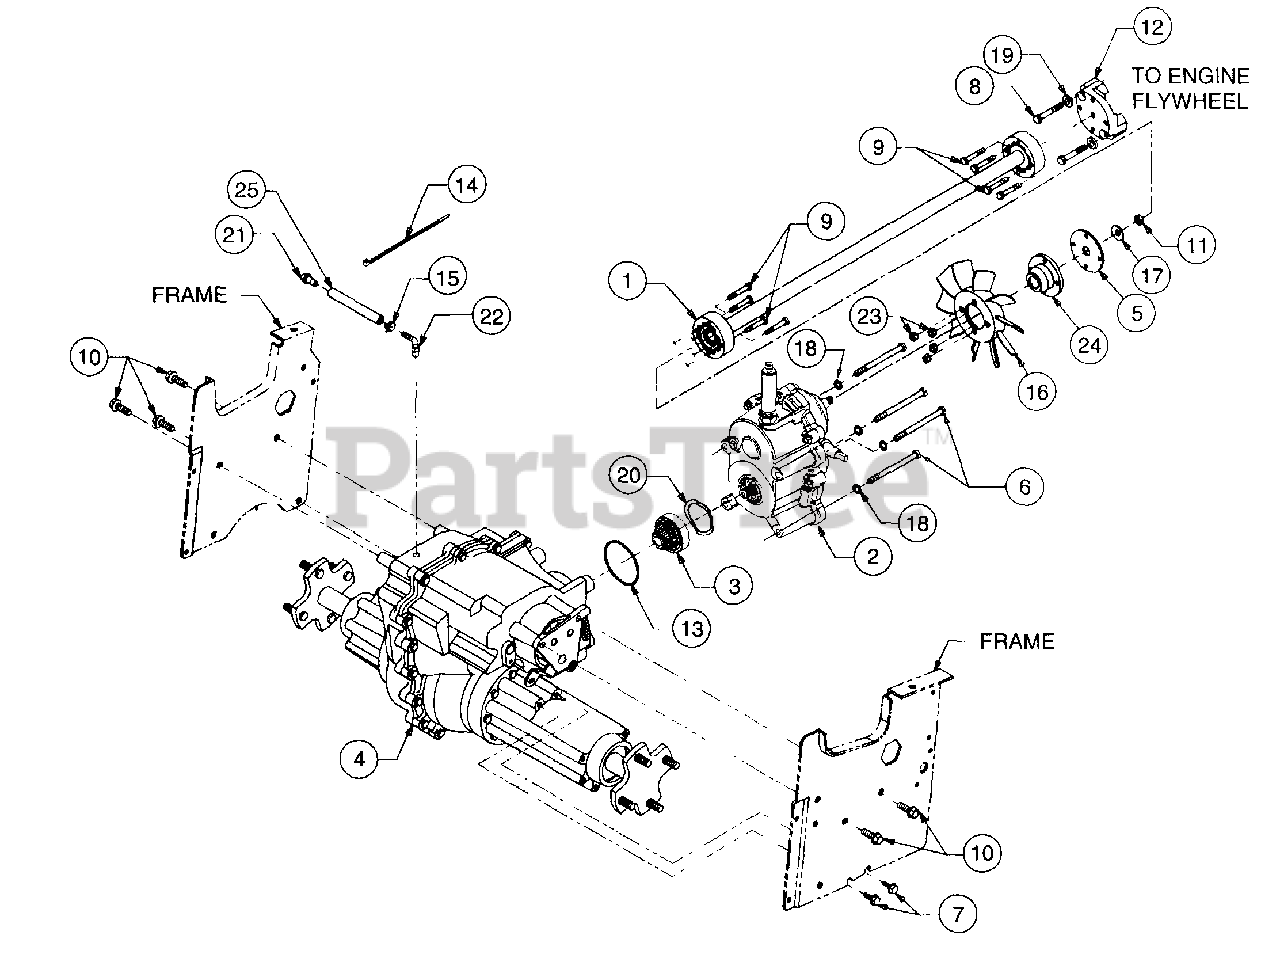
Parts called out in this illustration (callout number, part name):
1	Shaft Assy, Drive
2	Clutch Assembly
3	Pinion Assy, Input
4	Transmission Assy, 6-Speed
5	Plate, Drive Shaft Spacer
6	Screw, Hex Cap, 5/16-18 x 4.0 GR5
7	Screw, Hex Wash Hd Tapp 5/16-18 x .75
8	Screw, Hex Patch, M8-1.25 x 50mm
9	Screw, Hex Patch, 1/4-20 x 1.62 GR5
10	Screw, Hex Wash Hd Tp 3/8-16 x 1.25
11	Nut, Hex Center Lock Jam, 3/8-24
12	Adapter, Drive Shaft
13	O-Ring, 2.75 x .103
14	Tie, Self-Clinch Cable
15	Clamp, Hose
16	Fan, 10 Blade Cooling
17	Washer, Bell, .380 x .88 x .063
18	Washer, Lock, 5/16
19	Washer, Flat, .312 x .750 x .119
20	Washer, Spring Wave, 1.96 x 2.44 x .06
22	Fitting, Elbow
23	Nut, Fan, 1/4-20
24	Adapter, Clutch
25	Line, Fuel,
